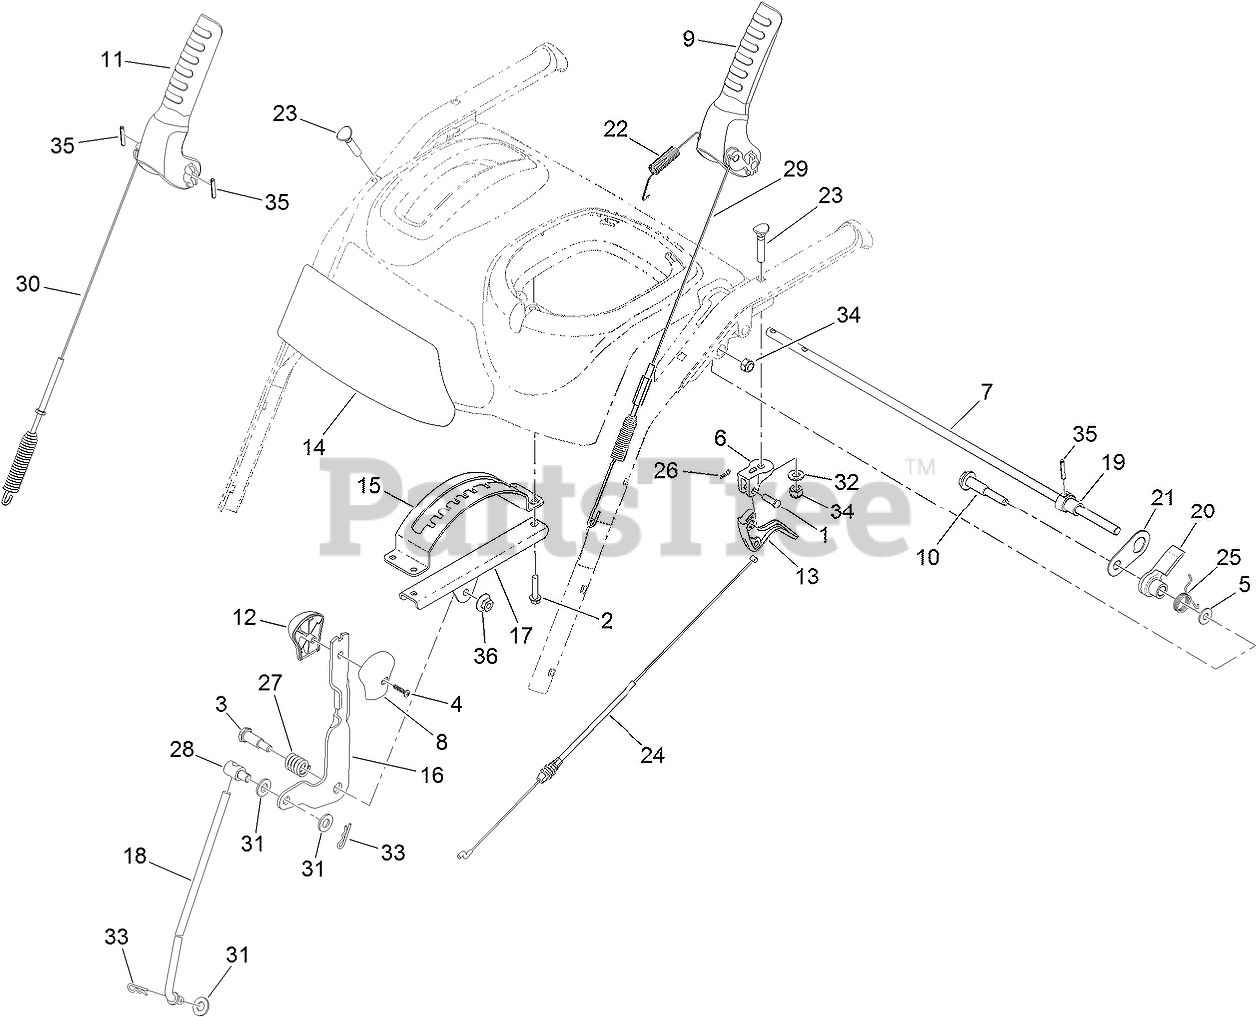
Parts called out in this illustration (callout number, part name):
1	PIN-CLEVIS
2	SCREW-PLASTITE
3	SCREW-SHOULDER
4	SCREW-PPH
5	WASHER-FLAT
6	MOUNT-CLUTCH, LEVER
7	ROD-LOCKOUT
8	KNOB-SHIFT, LH
9	LEVER-TRACTION
10	SCREW-SHOULDER
11	LEVER-AUGER
12	KNOB-SHIFT, RH
13	LEVER-CLUTCH
15	GUIDE-SELECTOR, SPEED
16	SELECTOR-SPEED
17	MOUNT-SELECTOR, SPEED
18	ROD-SHIFT
19	CAM-LOCKOUT
20	LATCH-LOCKOUT
21	LINK-LOCKOUT
22	SPRING-TENSION
23	SCREW-HANDLE
24	CABLE-CLUTCH
25	SPRING-TORSION
26	PIN-HAIR
27	SPRING-COMPRESSION
28	TRUNNION-ROD
29	CABLE-TRACTION
30	CABLE-AUGER
31	WASHER-FLAT
32	WASHER-FLAT
33	PIN-COTTER
34	NUT-LOCK, NI
35	PIN-SPRING
36	NUT-HF
